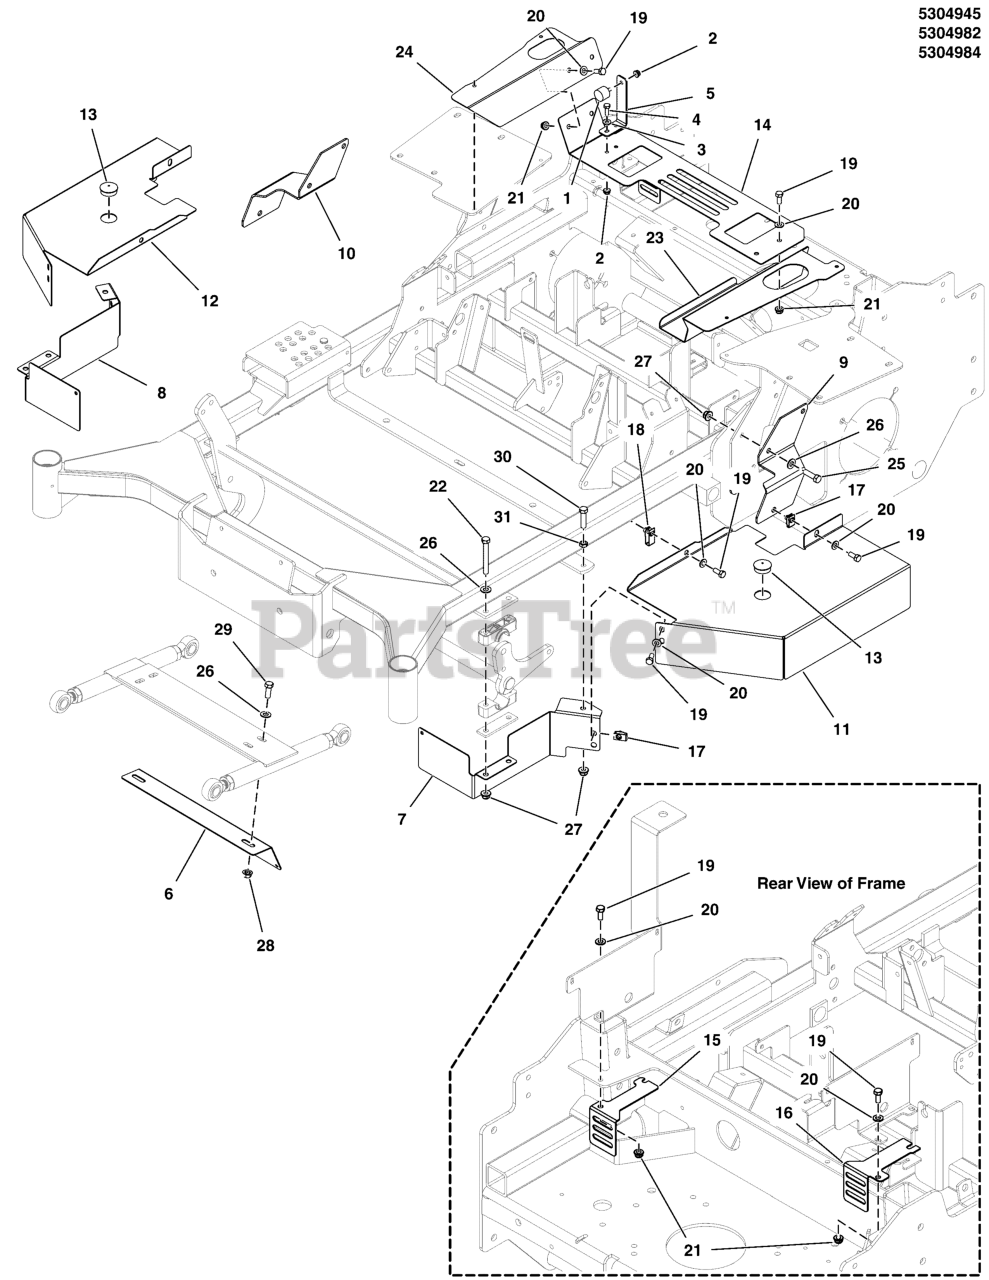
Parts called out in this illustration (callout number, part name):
1	BUMPER, RUBBER 1/4-20
2	NUT, 1/4-20 HEX NYLOCK FLANGE
3	WASHER, 1/4 SAE
4	BOLT, 1/4-20 X 3/4 GD5 CZ
5	PLATE, SEAT LOCK, CE - BLK
6	GUARD, PULLER BAR, CE - BLK
7	PLATE, GUARD MOUNT, LH FRONT - RED
8	PLATE, GUARD MOUNT, RH FRONT - RED
9	PLATE, GUARD MOUNT, LH REAR - RED
10	PLATE, GUARD MOUNT, RH REAR - RED
11	PLATE, DECK GUARD, UPPER, LH - RED
12	PLATE, DECK GUARD, UPPER, RH - RED
13	PLUG, PANEL, 1.25 - BLACK
14	PLATE, SEAT GUARD, CE - BLK
15	PLATE, FAN GUARD, LH CE - BLK
16	PLATE, FAN GUARD, RH CE - BLK
17	BODY CLIP, 5/16-18-7GA MATERIAL
18	BODY CLIP, 5/16-18 -1/4 MATERIAL
19	BOLT, 5/16-18 X 3/4 GD5
20	WASHER, 5/16" SAE
21	NUT, 5/16-18 HEX NYLOCK FLANGE
22	BOLT, 3/8-16 X 3" GD5 CZ
23	GUARD, CE SEAT, LH - BLK
24	GUARD, CE SEAT, RH - BLK
25	BOLT, 3/8-16 X 1-1/4" GD5 CZ
26	WASHER, 3/8 SAE
27	NUT, 3/8-16 HEX NYLOCK FLANGE
28	NUT, 3/8-16 HEX SERRATED FLANGE
29	BOLT, 3/8-16 X 1" GD5 CZ
30	BOLT, 3/8-16 X 1-1/2" GD5 CZ
31	NUT, 3/8-16 HEX JAM
